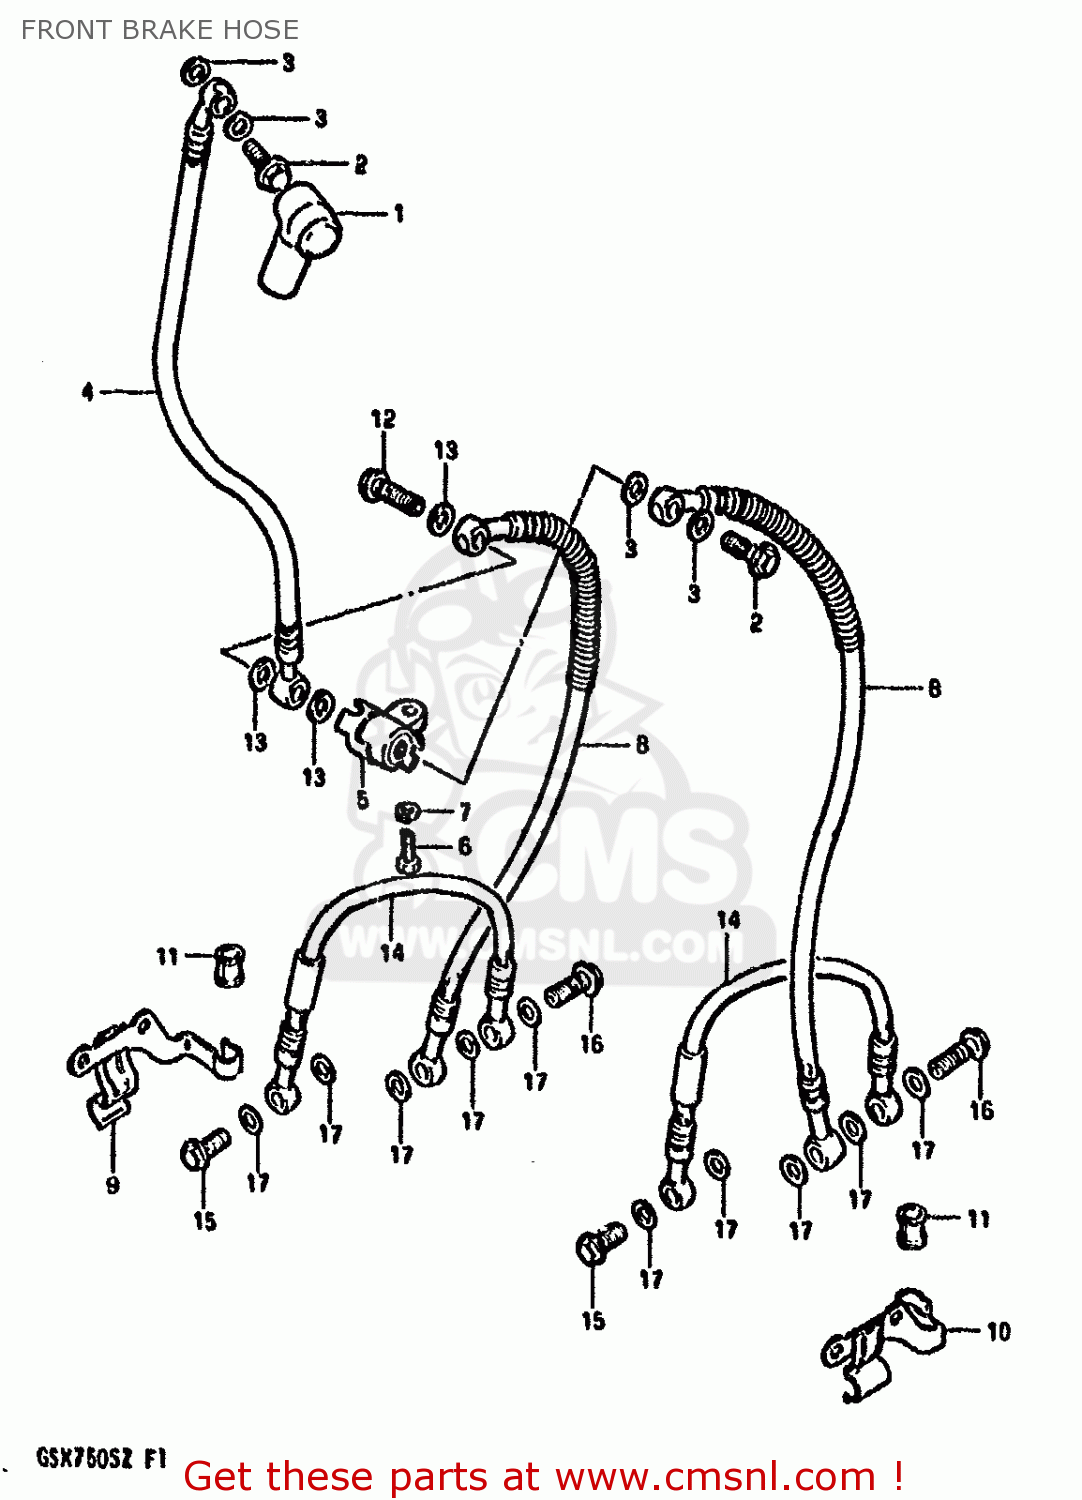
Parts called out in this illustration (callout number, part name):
1	BOOT
2	BOLT,UNION
3	WASHER
4	HOSE,BRAKE NO.1
5	JOINT,BRAKE HOSE
6	BOLT
7	LOCK WASHER
8	HOSE,FRONT BRAKE
9	CLAMP, HOSE RH
10	CLAMP, HOSE LH
11	BUSH,BRAKE HOSE GUIDE,NO.2
12	BOLT,UNION
13	WASHER
14	HOSE, ANTI NOSE
15	BOLT,UNION
16	BOLT,UNION
17	WASHER
